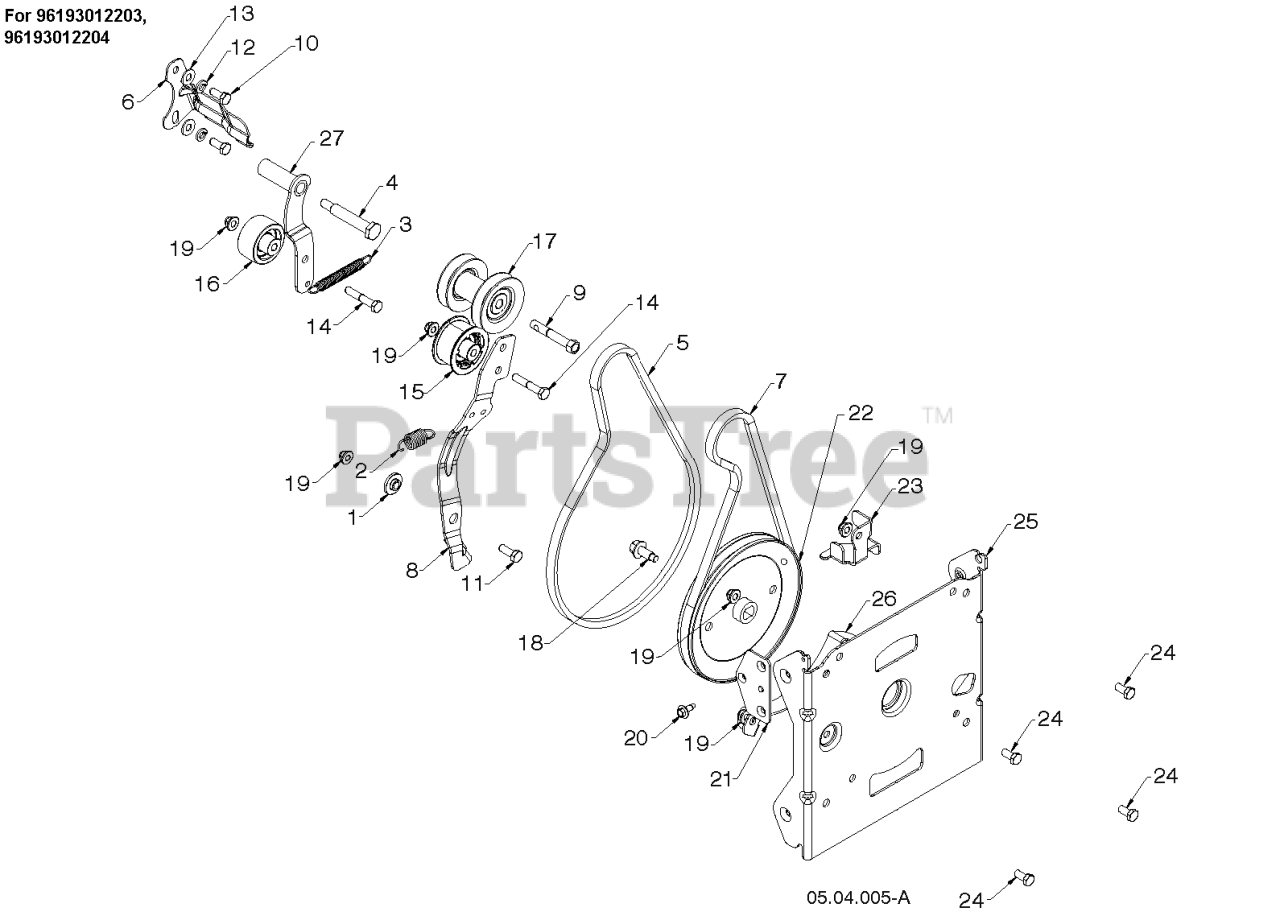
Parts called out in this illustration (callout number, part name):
1	BUSHING.BRAKE.ARM
2	SPRING RETURN, IDLER ARM, IMPE
3	SPRING RETURN IDLER ARM
4	BOLT 5/16-24X2.25 HEX HEAD SHO
5	BELT.DRIVE.SNOW.DUAL
6	BELT KEEPER BRACKET
7	LOW CRANK IMPELLER BELT
8	ARM.IDLER.AUTO-PH.676
9	BOLT.ENGINE.PULLEY
10	SCREW 5/16-24 X .75 GR5
11	BOLT HEXAGON BOLT 5/16-18 X 7/
11	BOLT
12	WASHER.LOCK.HVY.HLCL.SPR.5/16
12	BALL BEARING AUGER BALL BEARIN
13	WASHER 11/32 X 11/16 X 14 GA T
13	WASHER M
14	BOLT, HEX 5/16-18X1-3/4
15	PULLEYIDLER.2.0.W/SPACER.CZ
16	PULLEY.IDLER.FLNGLESS.W/SPACER
17	PULLEY.ASM.IMPELLER/DRIVE
18	SCREW HEXAGON HEAD FLANGE 3/8-
18	SCREW FLANGE HEAD CAP WITH DOG
19	NUT HEXAGON FLANGE 5/16-18 ST
19	NUTNYLOK.FLRANGE.5/16-18
20	HEX.WASHER.HEAD 1/4-20 X .65
21	BRACKET NUT BLACK ZINC PLATE
22	PULLEY IMPELLER DD 4L
23	GUIDE.LOWER.AUGER.BELT.479
24	Screws
24	BOLT, HEX HEAD 5/16-18
25	BRACKET.AUG.HOUSING.INTER.BLAC
26	BRACKET.BELT.KEEPER.LOWER.BLAC
27	ARM IDLER DRIVE WELDMENT_HOT
